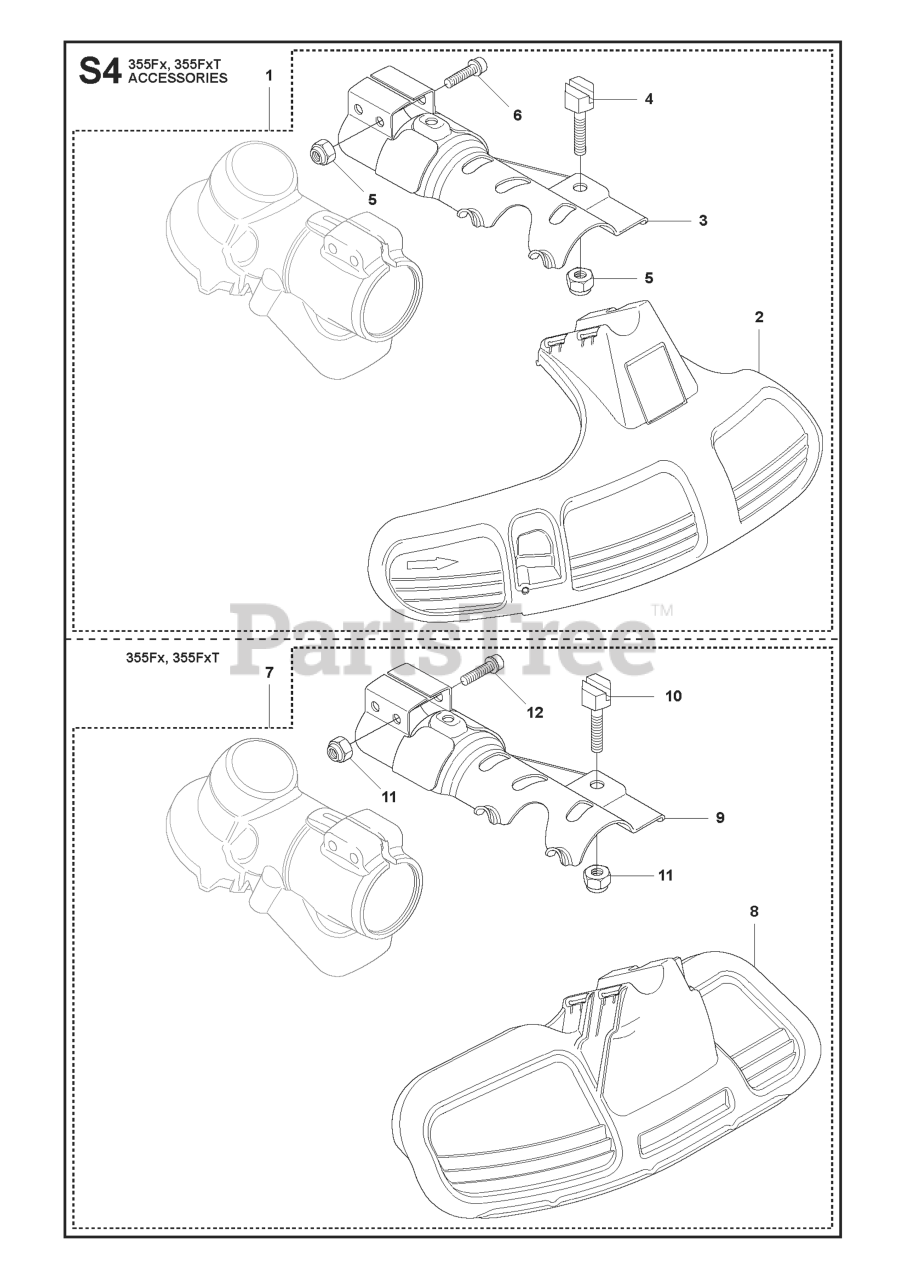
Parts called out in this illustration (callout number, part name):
1	GUARD ASSY
2	PROTECTION
3	ATTACHMENT PLATE
5	LOCKNUT M6
7	GRASS BLADE GUARD ADAPTER INCL
8	BLADE GUARD GRASS
9	ATTACHMENT PLATE
11	LOCKNUT M6
